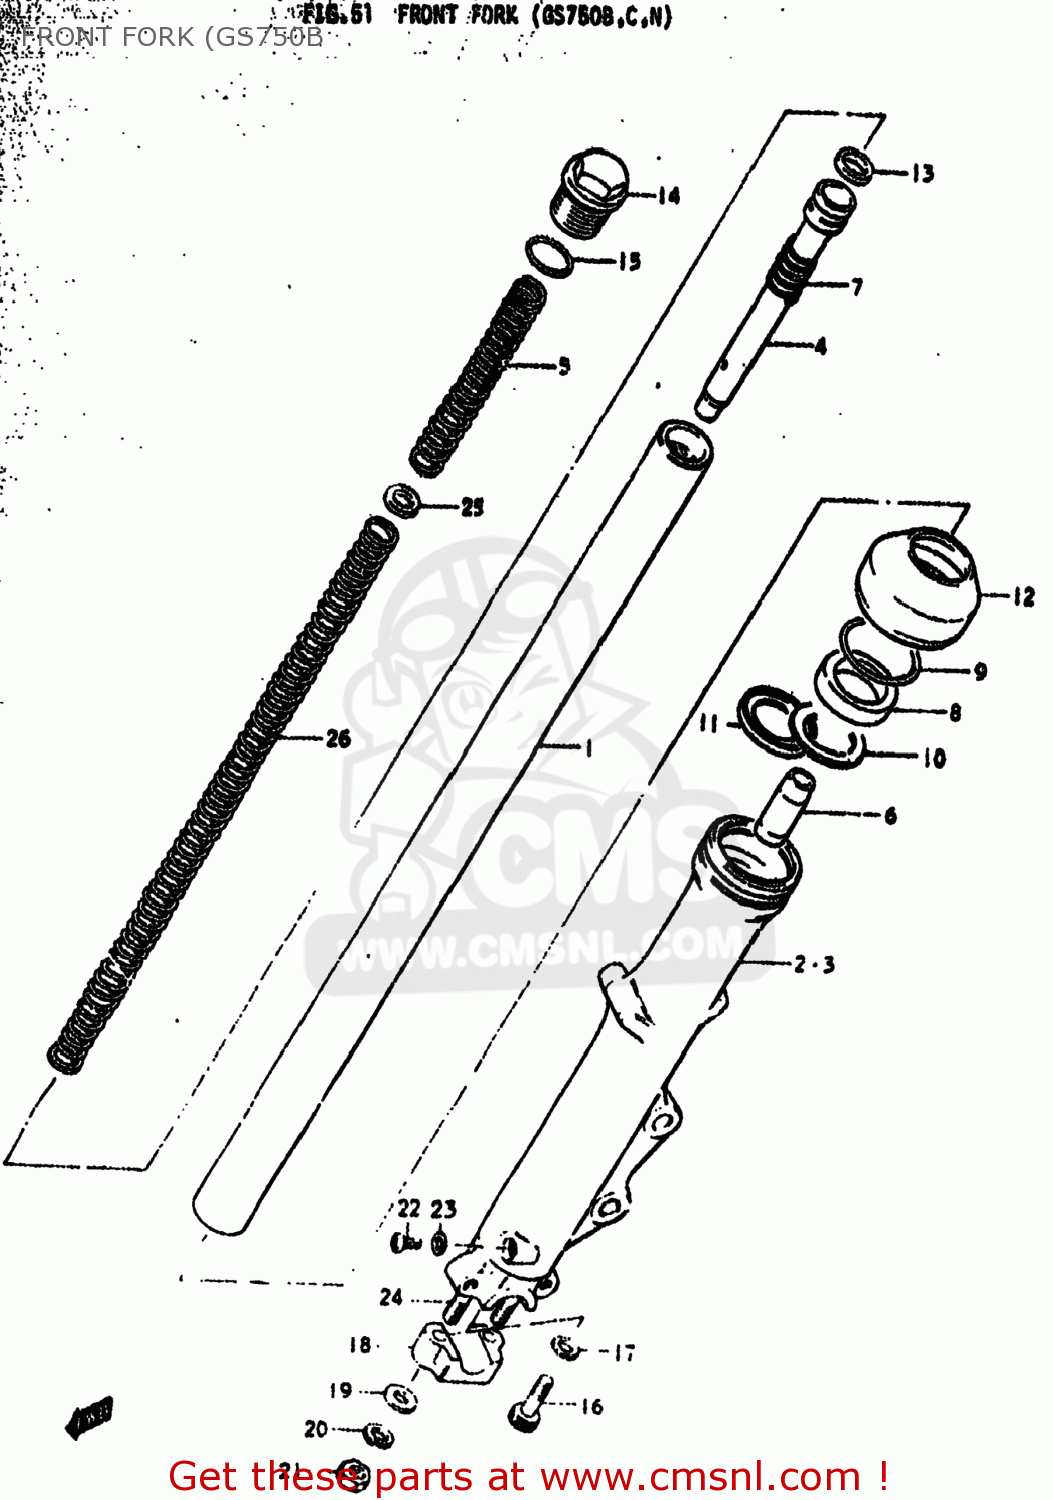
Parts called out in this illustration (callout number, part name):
0	DAMPER ASSEMBLY,RIGHT
1	TUBE,INNER
2	TUBE,FORK,OUTER,RIGHT
3	TUBE,FORK,LEFT,OUTER
4	CYLINDER,FRONT FORK
5	SPRING,FRONT FORK,UPPER
6	PIECE,OIL LOCK
7	SPRING,FORK REBOUND
8	OIL SEAL,FRONT FORK
9	RING,OIL SEAL STOPPER
10	SPACER,SEAL
11	SPACER,SEAL
12	BOOT
13	RING
14	CAP,INNER TUBE
15	O RING
16	BOLT
17	GASKET (NAS)
18	HOLDER,AXLE
19	WASHER
20	LOCK WASHER
21	NUT
22	SCREW
23	GASKET (NAS)
24	STUD 8X25
25	WASHER
26	SPRING,FRONT FORK
